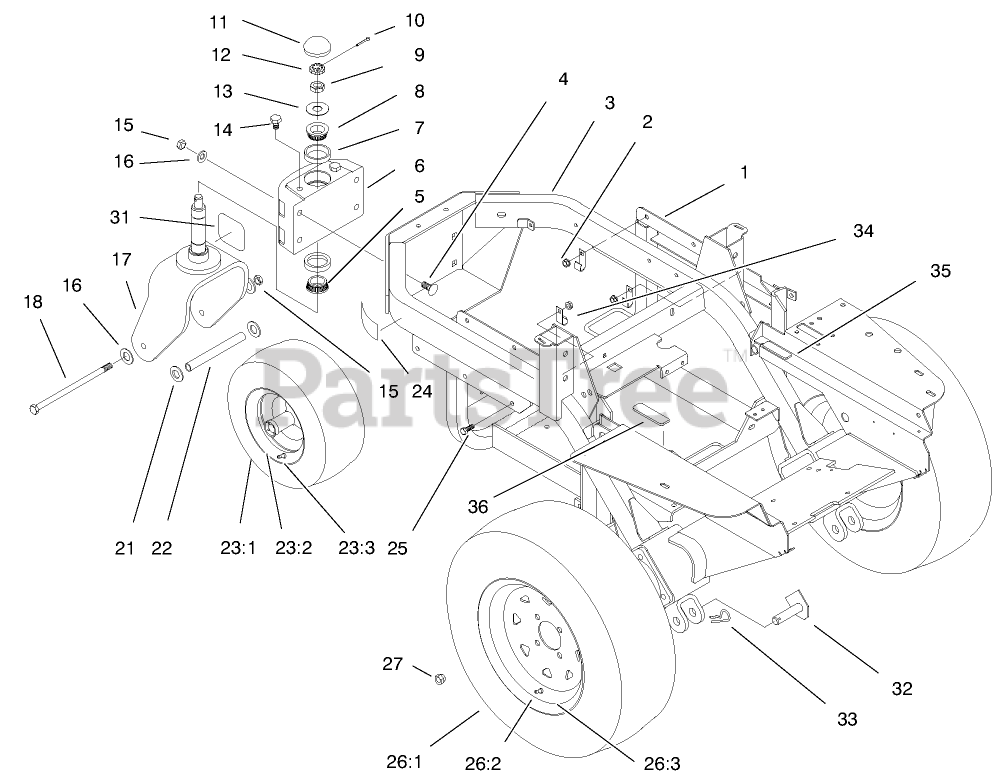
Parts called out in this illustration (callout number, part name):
1	ENGINE SUPPORT ASM
2	NUT-LOCK, NI
3	FRAME ASM W/ DECALS
4	SCREW-CARR
5	BEARING-CONE
6	HOUSING - SPINDLE
7	CUP-BEARING, ROLLER
8	BEARING-ROLLER, CONE
9	NUT-JAM
10	PIN-COTTER
11	DUSTCAP
12	NUT-LOCK, RETAINER
13	WASHER-FLAT
14	SCREW-HH
15	NUT-LOCK, NI
16	WASHER-FLAT
17	CASTER FORK ASM
18	SCREW-HH
19	DECAL - PATENT NUMBERS, OFZ
21	WASHER-FLAT
22	TUBE-SPACER, CASTOR
23:2	WHEEL ASM
23:3	STEM-VALVE
24	DECAL-HOT SURFACE
25	SCREW-HH
26:1	TIRE
26:2	STEM-VALVE
26:3	WHEEL
27	NUT-LUG
31	DECAL - Z320
32	PIVOT PIN ASM
33	PIN-HAIR
34	CLIP
35	PAD-RUBBER
36	DECAL-WARNING
